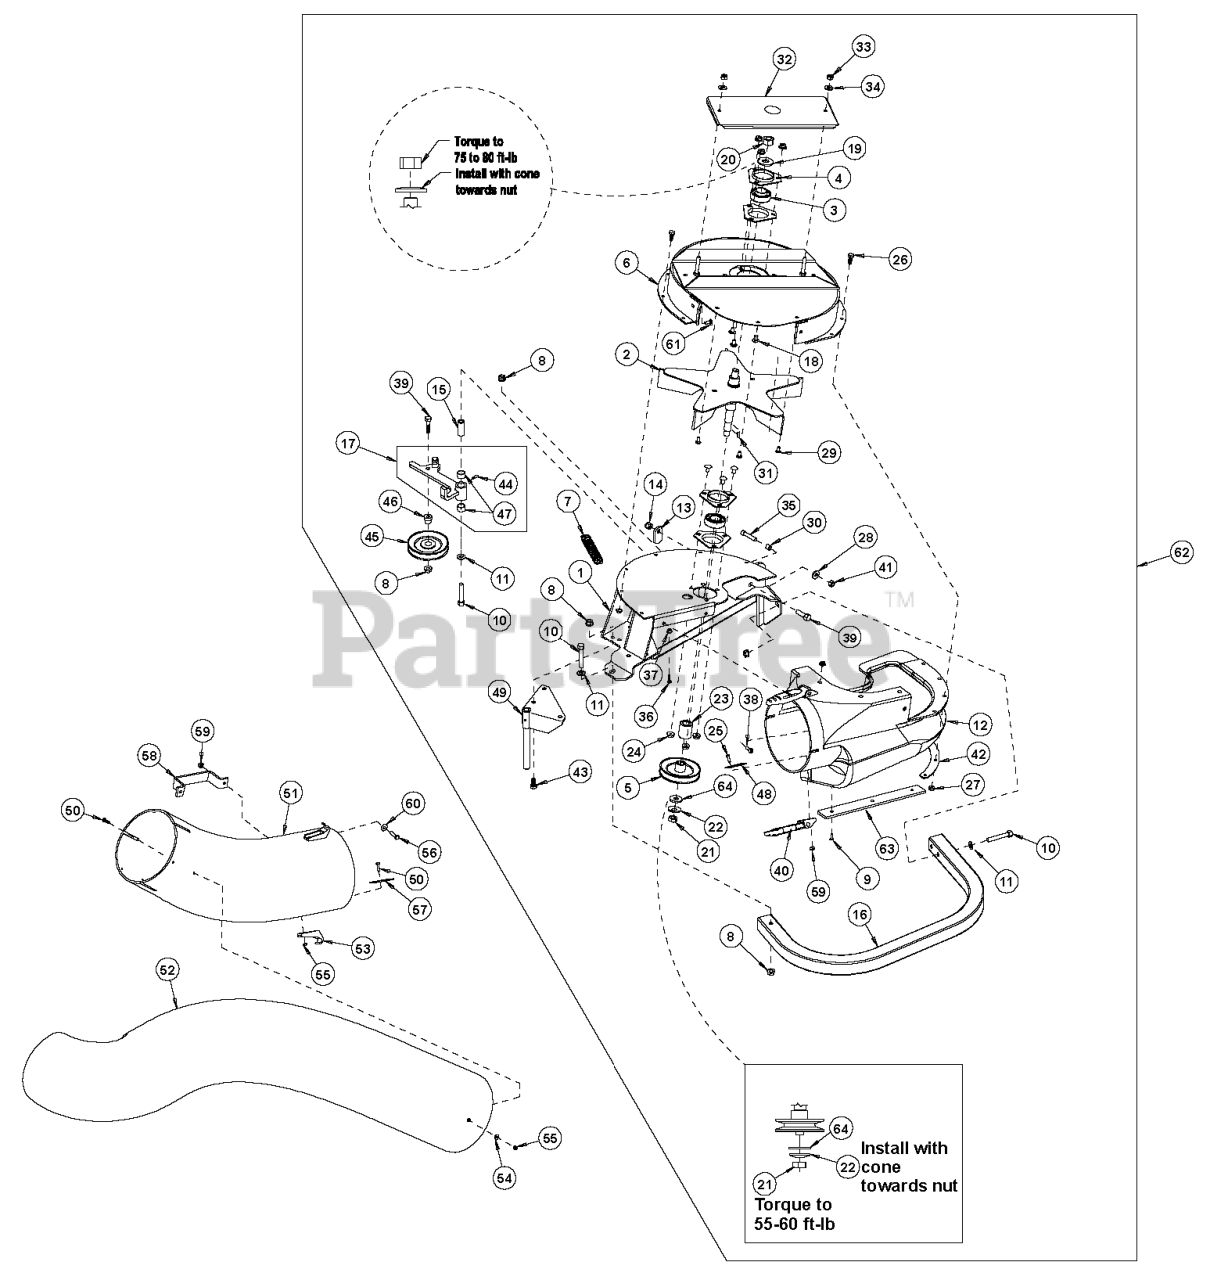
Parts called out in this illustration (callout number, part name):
1	WLD,BLOWER MOUNT
2	IMPELLER
3	BEARING
4	HOUSING-FLANGE
5	SHEAVE
6	ASM, UPPER HSG
7	SPRING-IDLER
8	NUT-HHF, WHIZ
9	RIVET-BLIND
10	SCREW-HH
11	WASHER-FLAT
12	ASM,BLOWER CHUTE LZ
13	LATCH-CATCHER, GRASS
14	NUT-LOCK, NI
15	BUSHING
17	ASM, IDLER ARM - SERVICE
18	SCREW-CARR
19	WASHER-SPRING
20	NUT-HEX
21	NUT-JAM
22	WASHER-SPRING
25	SCREW-HH
26	SCREW-HH
28	WASHER-SPRING
29	SCREW-CARR
30	BUSHING, LOCATOR
31	KEY-WOODRUFF
32	ASM, BEARING COVER
33	NUT-LOCK, NI
34	WASHER-FLAT
35	SCREW-HSH
36	SCREW-HEAD, TRUSS
39	SCREW-HH
40	LATCH-RUBBER
41	NUT-HEX
42	PLATE-BACKING, BLOWER
43	SCREW-HH
44	FITTING-GREASE
46	HUB,SPACER
47	BUSHING
48	PLATE-BACKING
49	PIN-MOUNT
50	SCREW-HWH
51	TUBE-LOWER
52	TUBE-UPPER
53	LATCH-CATCH
54	WASHER-FLAT
55	NUT-LOCK, NI
56	SCREW-HH
57	PLATE-BACKING
59	NUT-LOCK, NI
60	WASHER-FLAT
61	BOLT-CARR
62	Asm, Blower
63	PLATE,REINFORCEMENT LARGE
64	WASHER-FLAT
65	NUT-LOCK, NI
